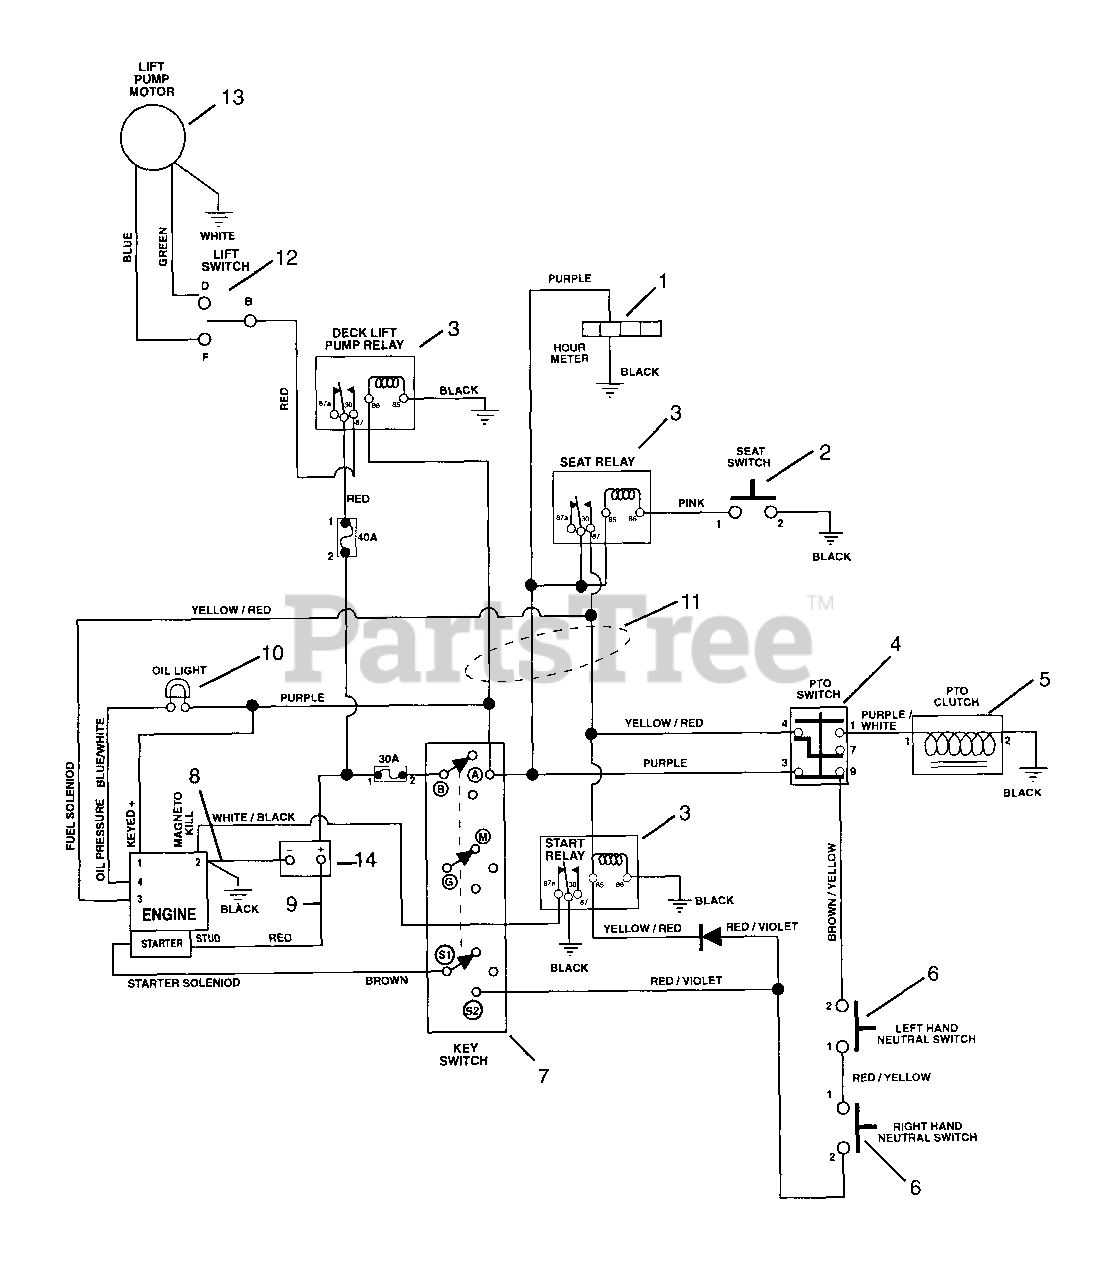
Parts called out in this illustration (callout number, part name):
1	Hour Meter
2	Switch-Seat
3	Relay
4	Switch-Clutch w/Retainer Ring
5	Clutch-Electric Warner
6	Switch-Neutral Start N.O.
7	Key Switch
8	Start Cable 22"
9	Cable-Negative Battery
10	Light-Indicator
11	Harness-Wiring 18 HP Kohler
12	Switch Assembly
13	Pump-Electric Hydraulic
